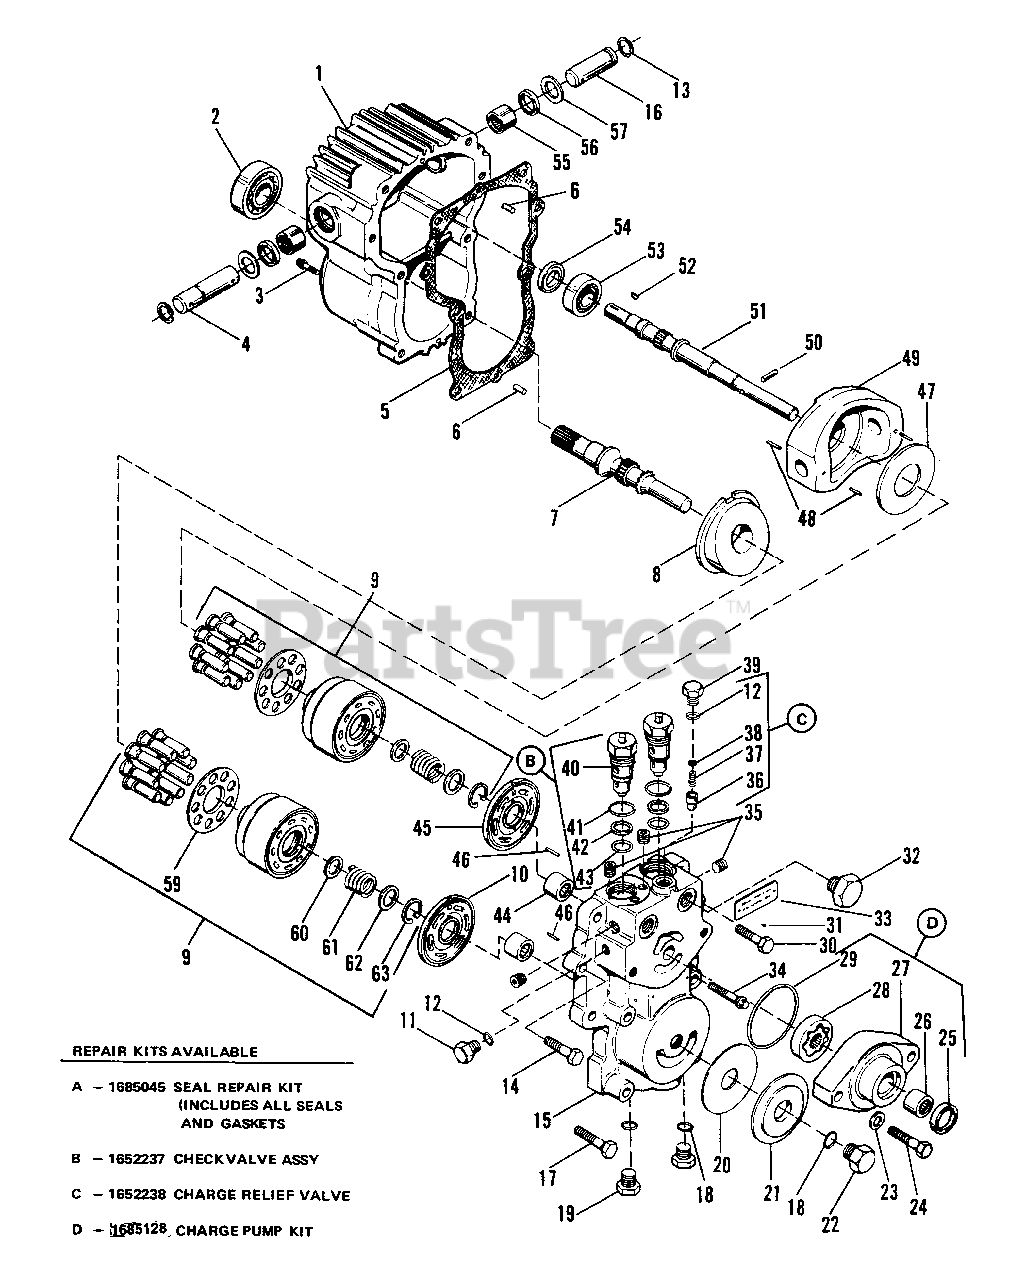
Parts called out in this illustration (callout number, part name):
2	BEARING, Ball
3	CAPSCREW, 12 Pt.
6	PIN, Str. Headless
7	SHAFT, Motor
8	PLATE, Swash
9	CYLINDER BLOCK KIT
10	VALVE, Plate
11	PLUG, Hex Hd.
13	RING, Retaining
14	CAPSCREW, Hex Hd.
15	SECTION, Center
17	CAPSCREW, Hex Hd.
19	PLUG, Hex Hd.
21	COVER PLATE, Filter
22	PLUG, Special
23	WASHER, Flat
24	CAPSCREW, Hex Hd.
26	BEARING, Needle
27	HOUSING, Charge Pump
28	GEROTOR ASSY
30	CAPSCREW, Hex Hd.
31	SCREW, Drive
32	PLUG, Str. Thd., Hex
33	PLATE, Name
34	CAPSCREW, 12 Pt.
36	CONE, Relief Valve
37	SPRING, Relief Valve
39	PLUG, Hex Hd.
40	CHECK VALVE ASSY
42	RING, Back-up
44	BEARING, Needle
45	PLATE, Valve
46	PIN, Str. Headless
47	PLATE, Thrust
48	PIN, Coiled Spring
49	PLATE, Swash
50	PIN, Str. Headless
51	SHAFT, Pump
52	KEY, Woodruff
53	BEARING, Ball
55	BEARING, Needle
57	WASHER, Special
59	RETAINER, Slipper
60	WASHER, Front
62	WASHER, Rear
63	RING, Retaining
